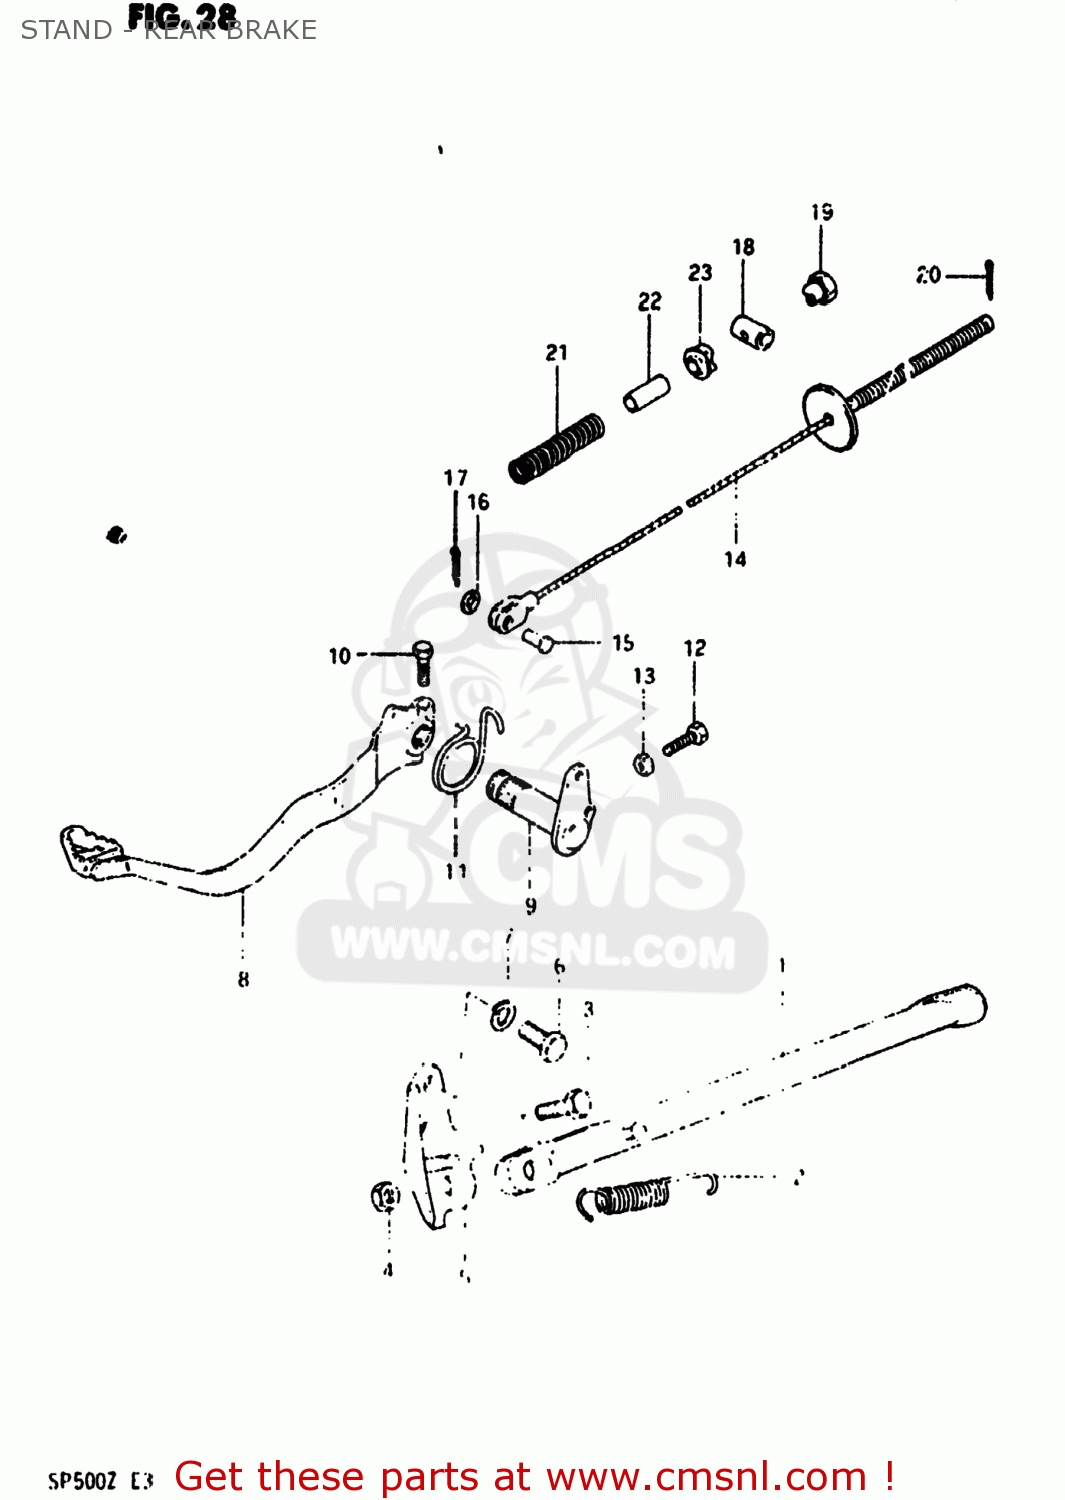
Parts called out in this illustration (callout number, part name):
1	STAND,SIDE
2	SPRING
3	BOLT(10X30)
4	NUT
5	BRACKET,PROP STAND
6	BOLT(10X19)
7	LOCK WASHER
8	PEDAL,BRAKE
9	ARM,BRAKE PEDAL
10	BOLT
11	SPRING
12	BOLT(6X23)
13	NUT
14	CABLE,RR BRAKE
15	PIN(L:17.5)
16	WASHER
17	PIN
18	PIN,BRAKE CABLE ADJUSTER
19	NUT
20	PIN
21	SPRING
22	CUSHION,FR GRILLE,UPPER
23	CUSHION
